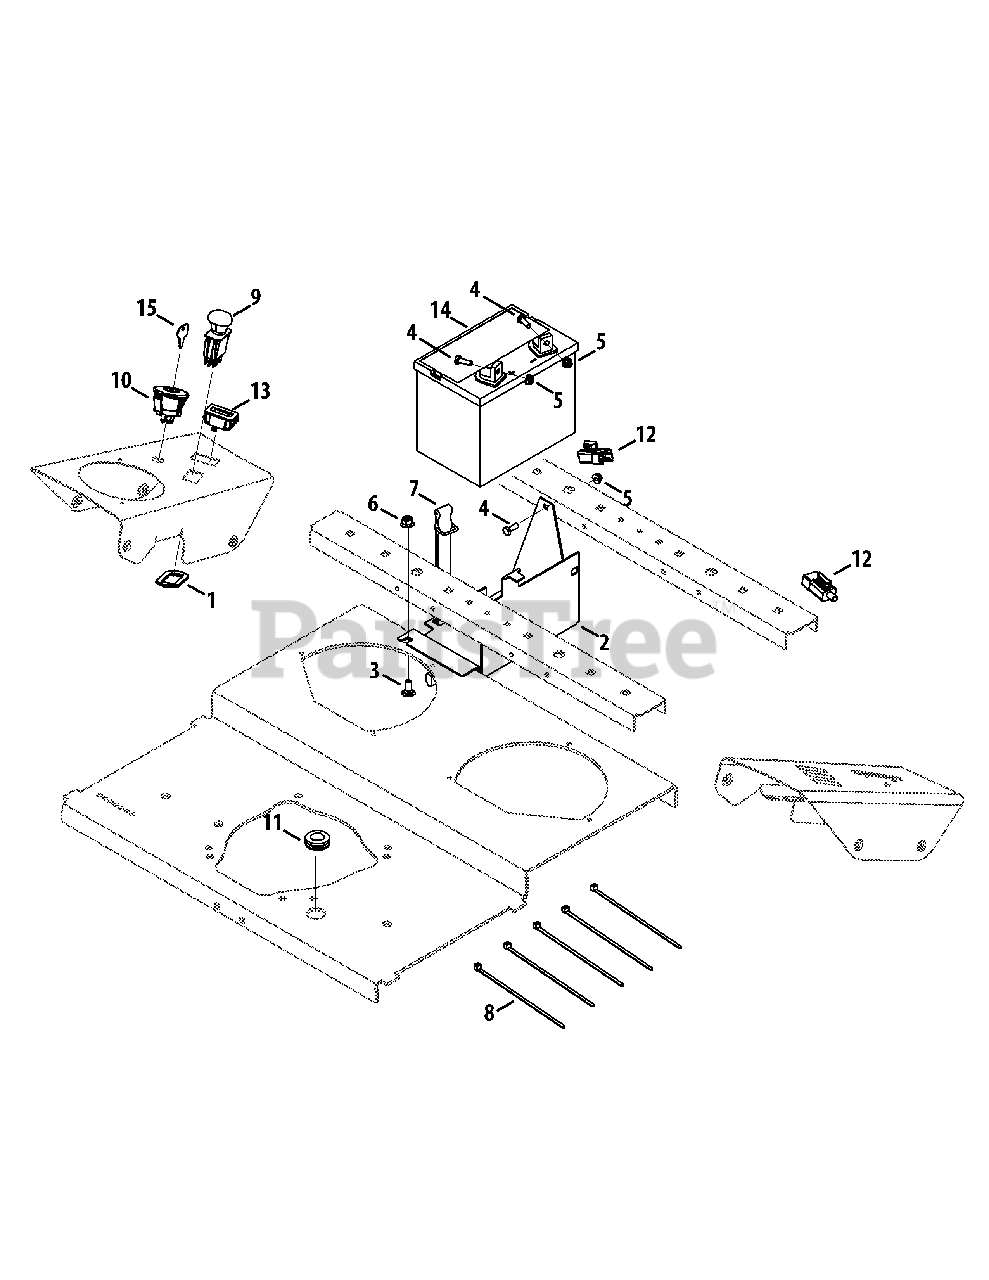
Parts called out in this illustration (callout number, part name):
1	PTO Switch Bracket
2	Battery Bracket
3	Carriage Bolt, 3/8-16 x .750
4	Hex Cap Screw, 1/4-20 x .75
5	Nut, 1/4-20, Flangelock
6	Nut, 3/8-16, Flangelock
7	Battery Strap
8	Cable Tie
9	Electric PTO Switch
10	Key Switch
11	Rubber Grommet, .75 x 1.062 x .50
12	Plunger Switch, NO/NC
13	Hour Meter
15	Key, Assembly
